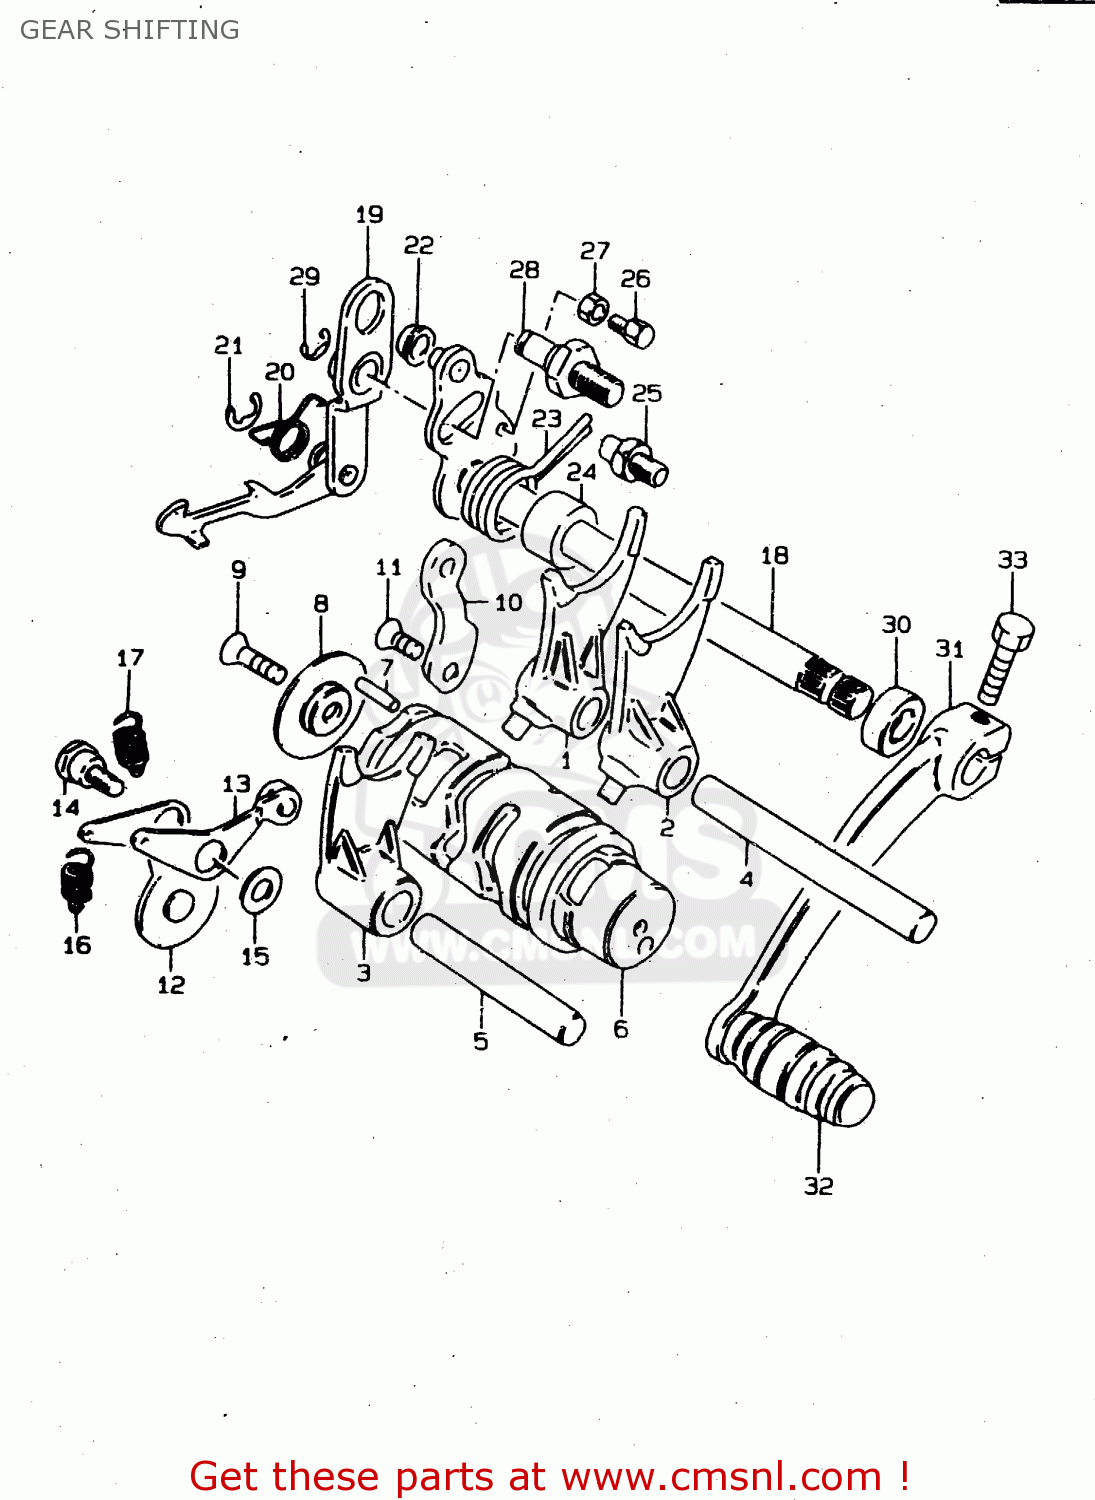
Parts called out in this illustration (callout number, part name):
1	FORK,GEAR SHIFT NO.1
2	FORK,GEAR SHIFT NO.2
3	FORK,GEAR SHIFT NO.2
4	SHAFT,GEAR SHIFT FORK
5	SHAFT,GEAR SHIFT FORK
6	CAM,GEAR SHIFT
7	PIN
8	RETAINER,GEAR SHIFT CAM DR PIN
9	SCREW
10	GUIDE,GEAR SHIFT CAM
11	SCREW
12	STOPPER,GEAR SHIFT CAM
13	STOPPER,GEAR SHIFT CAM NEUTRAL
14	BOLT(6X18.3)
15	WASHER
16	SPRING
17	SPRING
18	SHAFT,GEAR SHIFT
19	PAWL,GEAR SHIFT
20	SPRING
21	E-RING
22	SPACER(7X10X5)
23	SPRING
24	SPACER(12X20X15.3)
25	STOPPER,GEAR SHIFT CAM
26	BOLT,GEAR SHAFT RETURN SPR SET
27	NUT
28	STOPPER,GEAR SHIFT CAM
29	E.RING
30	OIL SEAL
31	LEVER ASSY,GEAR SHIFT
32	RUBBER,GEAR SHIFT PEDAL
33	BOLT
